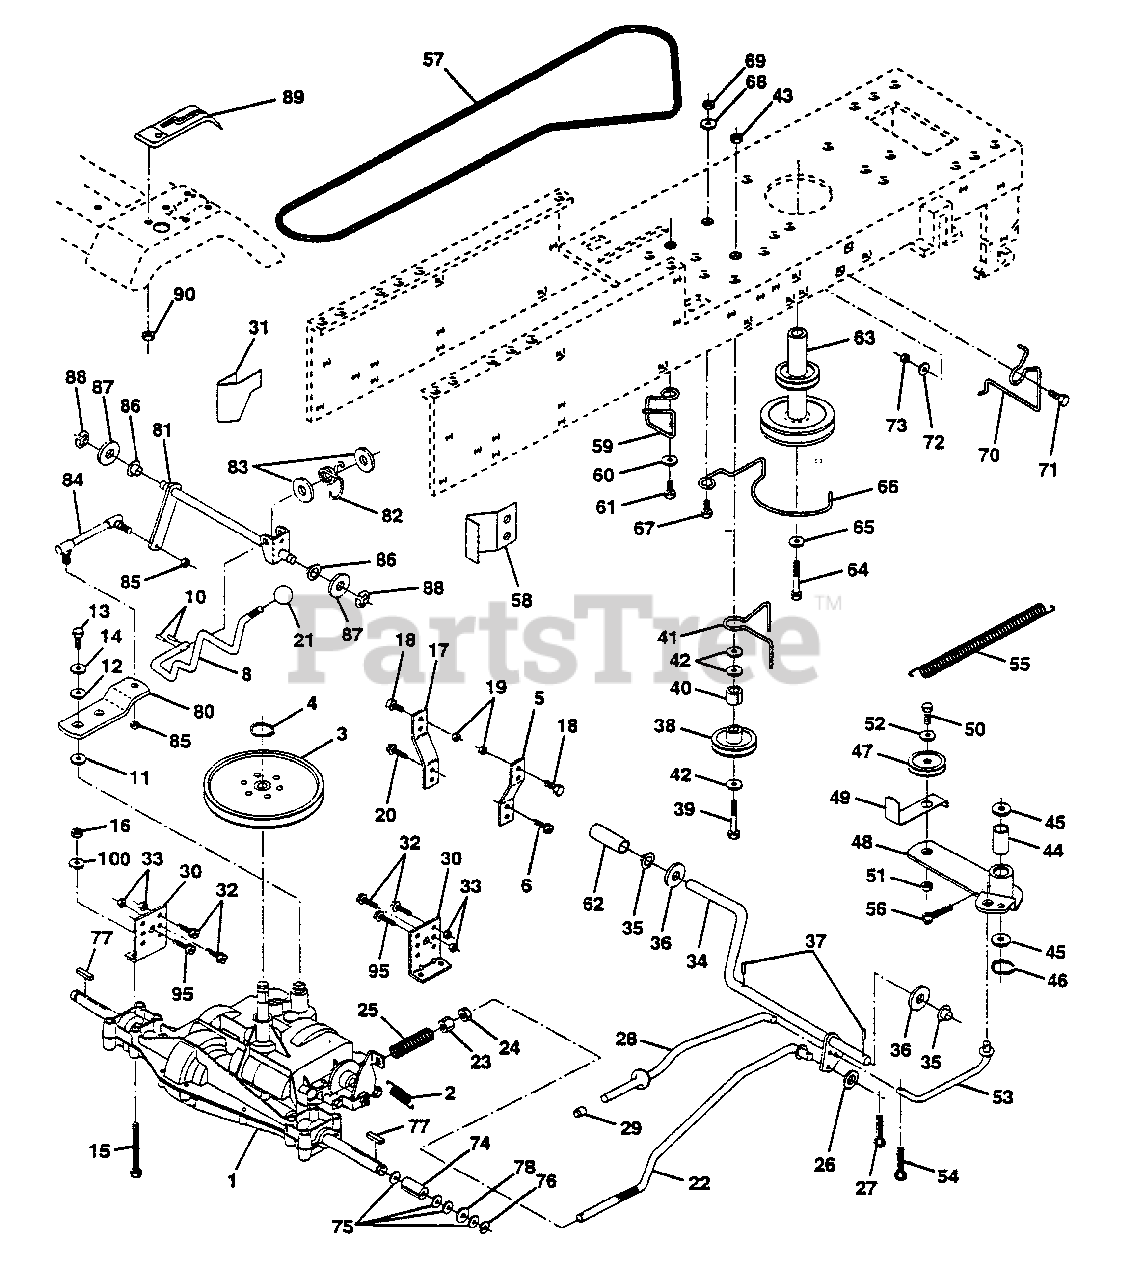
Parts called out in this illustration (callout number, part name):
1	Transaxle 6sp Model No. 4360-79
2	Spring Return Brake T/a Zinc
3	Pulley Transaxle 18" tires
4	Ring Retainer # 5100-62
5	Strap Torque 30 Degrees
6	Screw Thdrol 5/16-18 X 3/4 TYT
7	Bracket Saddle Shift
8	Rod Shifter
9	Washer 15/32 x 3/4 x 16 Ga.
10	Pin Cotter 1/8 X 1 Cad
11	Washer Plate Shf 388 Sq Hole
12	Washer 9/32 X 3/4 X 10 Ga
13	Bolt Fin Hex 1/4-28unfx3/4 Gr8
14	Washer Lock Hvy Helical 1/4
15	Bolt Fin Hex 5/16-18 UNC x 2.75
16	Nut Hex W/Ins Lock 5/16-18
17	Strap Torque LT
18	Bolt Fin Hex 3/8-16unc X 1 Gr. 5
19	Nut Hex Lock W/Ins 3/8-16 Unc
20	Screw Thdrol 5/16-18 X 3/4 TYT
21	Knob Duckhead 1/2-13 UNC
22	Rod Brake Blk Zinc 27 326
23	Nut Lock Hex W/wsh 3/8-16unc
24	Nut Hex Jam 3/8-16 Unc
25	Spring Rod Brake 2 00 Zinc
26	Washer 13/32 X 13/16 X 16 Ga
27	Pin Cotter 1/8 X 3/4 Cad
28	Rod Brake Parking LT
29	Cap Brake Parking Black
30	Bracket Mtg Transaxle
31	Keeper Belt LH LT 14 Ga
32	Bolt Hex Hd 5/16-18unc X 3/4
33	Nut Hex W/Ins Lock 5/16-18
34	Shaft Asm Pedal Foot 1 930
35	Bearing Nylon Blk 629 Id
36	Washer 21/32 X 1 X 16 Ga
37	Pin Roll 3/16 X 1"
38	Pulley Idler Flat
39	Bolt Fin Hex 3/8-16unc X 2-3/4
40	Spacer Split 395 X 59 Bzp
41	Keeper Belt Retainer
42	Washer 13/32 X 13/16 X 12 Ga
43	Nut Lock Hex W/Ins 3/8-16 Unc
44	Bearing Nyl 503 X 628 X 1 25
45	Washer Hardened
46	Ring Klip #t5304-50
47	Pulley Idler V Groove Plastic
48	Bellcrank Asm Clutch
49	Retainer Belt Style Spring
50	Bolt Hex Hd 3/8-16unc X 1-1/2
51	Nut Crownlock 3/8-16 Unc
52	Washer 13/32 X 13/16 X 16 Ga
53	Link Clutch 7 66
54	Pin Cotter 1/8 X 3/4 Cad
55	Spring Return Clutch 6 75
56	Pin Cotter 1/8 X 3/4 Cad
57	V-Belt Ground Drive 95 25 42"
58	Keeper Belt RH LT Pnt/zinc 16g
59	Keeper Belt Chassis Span Ctr
60	Washer 13/32 X 13/16 X 12 Ga
61	Screw Thdrol 3/8-16x3/4 Ty-tt
62	Cover Pedal Blk Round
63	Engine Pulley
64	Bolt Hex 7/16-20x4 Gr 5
65	Washer Lock Hvy Hlcl Spr. 7/16
66	Keeper Belt Engine LH LT
67	Bolt Fin Hex 3/8-16unc X 1
68	Washer 13/32 X 13/16 X 12 Ga
69	Nut Crownlock 3/8-16 Unc
70	Guide Belt Mower Drive RH
71	Bolt Fin Hex 3/8-16unc X 1
72	Washer 13/32 X 1-1/4 X 12 Ga
73	Nut Crownlock 3/8-16 Unc
74	Spacer Axle
75	Washer 25/32 X 1 1/4 X 16 Ga.
76	E-ring #5133-75
77	Key Square 2 0 X 1845/1865
78	Washer 25/32 X 1-5/8 X 16 Ga
95	Screw Thdrol 3/8 - 16 x 3/4
100	Washer 11/32 x 3/4 x 16 Ga.
